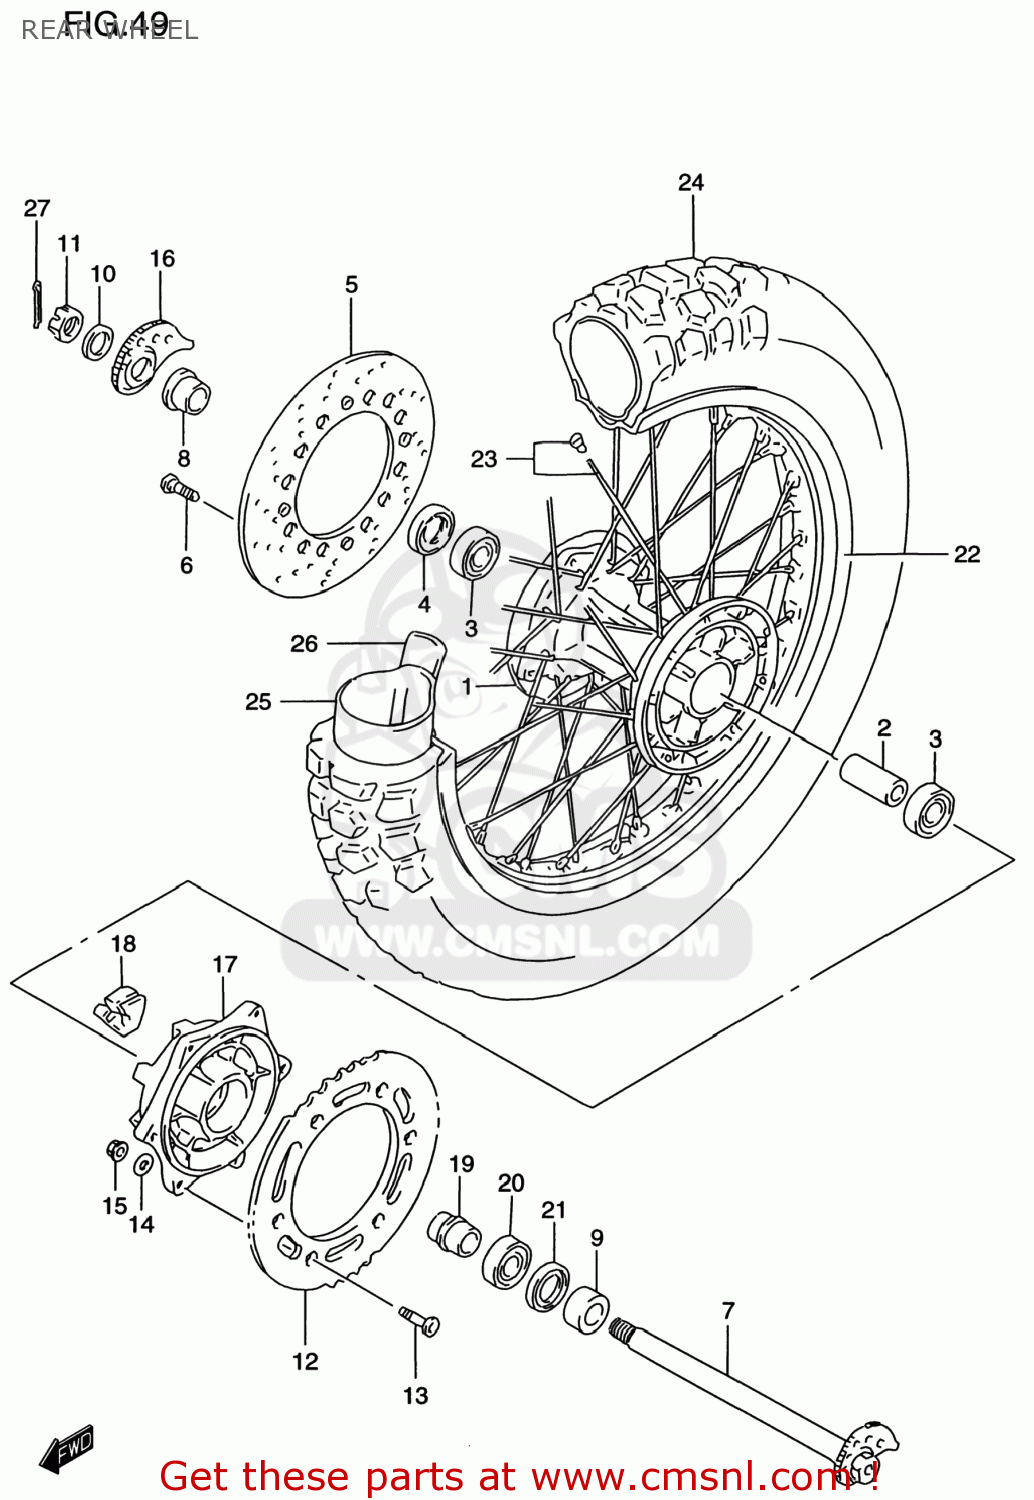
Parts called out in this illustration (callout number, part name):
1	HUB,RR WHEEL
2	SPACER,RR HUB BEARING
3	BEARING
4	SEAL,OIL(26X47X5)
5	DISC,RR BRAKE
6	BOLT,BRAKE DISC
7	AXLE,RR
8	SPACER,RR AXLE,R
9	SPACER,RR AXLE,L
10	WASHER(19X32X3.2)
11	NUT
12	SPROCKET,RR(NT:42)
13	BOLT(8X30.5)
14	WASHER
15	NUT
16	ADJUSTER,CHAIN,R
17	DRUM,RR SPROCKET MOUNTING
18	ABSORBER,RR HUB SHOCK
19	RETAINER,RR SPROCKET DRUM
20	BEARING(25X52X15)
21	SEAL,OIL(34X52X6)
22	RIM,REAR WHEEL (17XMT2.50)
23	SPOKE SET,RR WHEEL
24	TIRE,RR(120/90-17 64S)
25	TUBE ASSY,WHEEL INNER
26	PROTECTOR,WHEEL,INNER
27	PIN,COTTER
